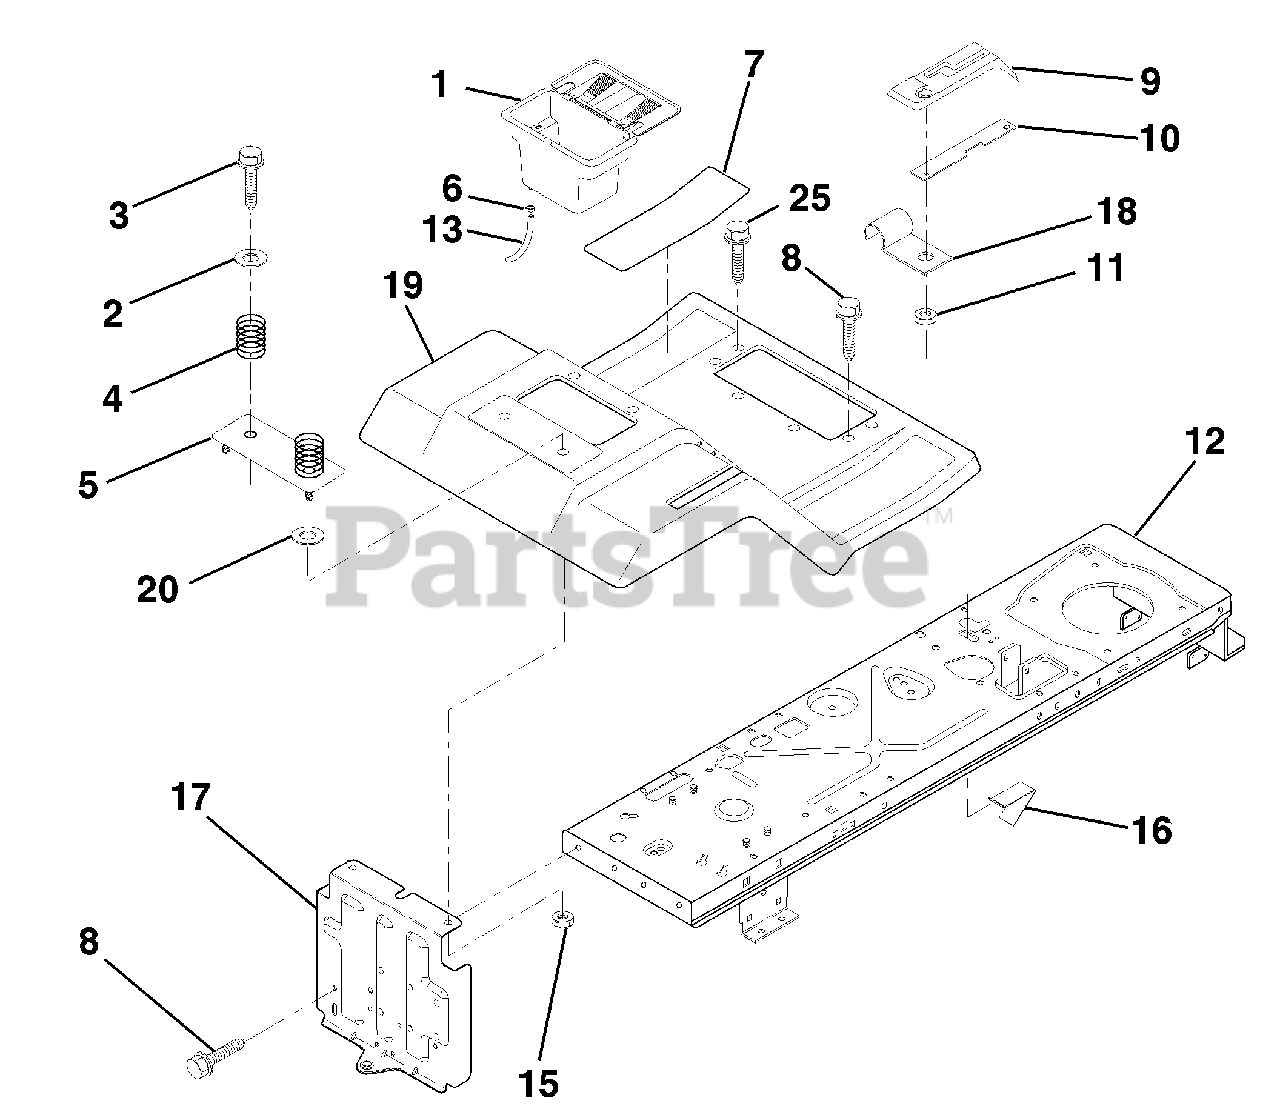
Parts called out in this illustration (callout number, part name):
1	Case, Battery
2	Washer 13/32 x 1-1/4 x 12 Ga.
3	Screw, Hex Wsh. Thrdrol. 3/8-16 x 3/4
4	Spring, Compression, Seat
5	Plate, Asm. Battery
6	Clamp, Hose
7	Pad, Footrest
8	Screw, Hex Wsh Thdrol. 5/16-18 x 3/4
9	Console, Shift Control
10	Bar, Shift Lock
11	Nut, Self-Thrd., Wsh. Head 3/16
12	Assembly, Frame
13	Tube, Battery Drain
15	Nut, Keps Hex 1/4-20 UNC
16	Switch Actuator
18	Clip, Insulated
19	Fender/Footrest
20	Washer 9/32 x 7/8 x 13 Ga.
25	Screw Hex Wsh Thdroll 5/16-18 x 1
